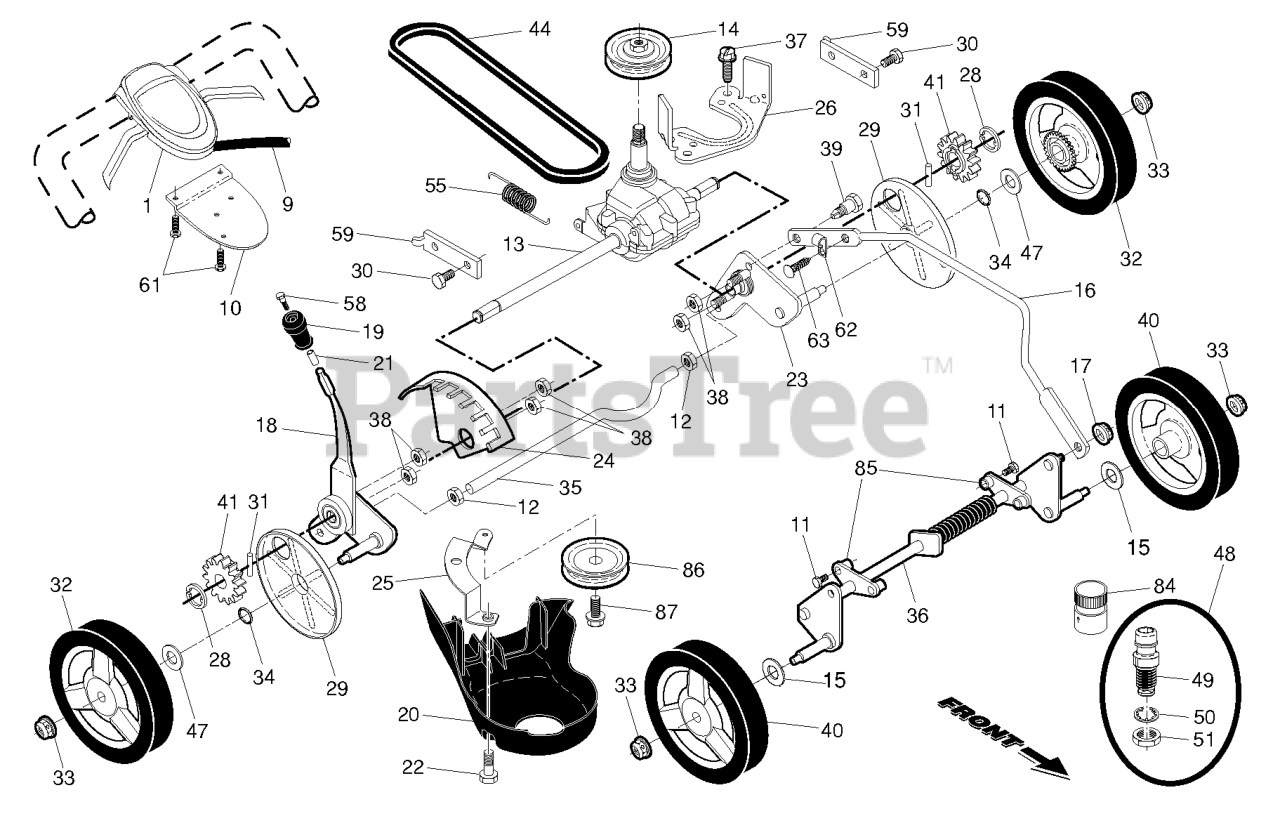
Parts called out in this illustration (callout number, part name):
1	CONTROL.AW2.22+RG.BS.GEN.BK/BK
9	CABLE.DRIVE.RWD.WALK.
10	BRACKET.DRIVE.CONTR.GEN2.BLACK
11	SCREW.HX.13X.750
12	NUT.HEX.1/2-20
13	TRANMISSION.ASM.22+RGD.W/IDLER
15	WASHER.FLAT.1/2
16	ROD.CONNECTING.RGD.22+.HW.BLAC
17	NUT.LOCK.5/16-18
19	KNOB.SEL.SPRING.22+.SP.RIB.BLK
20	COVER.REAR.DRIVE.22+2013
21	SCREW.PLASTIC.ANCHOR.5/16
22	BOLT.5/16HEX.WHS.HD
23	Wheel Axle Assembly, LH
24	BRACKET.WHL.ADJ.9.POS.W/PAD
25	BRACKET.DRIVE.COVER.RGD.
26	BRACKET.TRANS.BELT.KEEPER.BZP
28	E-RING 7/16 RE
29	COVER.DUST.WHEEL.INNER.WALK
30	BOLT.5/16HEX.WHS.HD
31	PAWL, DRIVE
32	WHEEL.8X1.75.3SPK.RAD3.GREY
33	NUT.HEX.FLANGE.3/8-16.LO(3 2)
34	O-RING..070X.487.NEOPRENE
35	AXLE.REAR.RGD
36	AXLE.ASM.FRT.RGD.BZP
38	NUT.HEX.FLANGE.1/4
39	SHOULDER BOLT SEMI GIMLET PT.
40	WHEEL AND TIRE ASSY, REAR
41	PINIION.14.TOOTH.RGD
44	RP.BELT.DRIVE.RGD.SS.WALK
47	WASHER FLUT
48	KIT.WASH-OUT.PORT.ZINC.WALK
49	FITTING, HOSE, WATER WASHOUT
50	WASHER.LOCK.INTERNAL.TOOTH
51	LOCKNUT.HEX.WITH.O-RING
55	SPRING.RETURN.AUTO.
58	SCREW.12-14X1.500
59	BRACKET.SUPPORT.22+RWGD.BZP
61	SCREW, PHILLIPS HEAD 10 X 5/8
62	CLIP.CABLE.BLK
63	FASTENER.PUSH.O.250X0.783
84	COUPLING.QUICK CONNECT
85	BRACKET.FRT.AXLE.SUPPORT
86	RP PULLEY.AWD.IDLER
